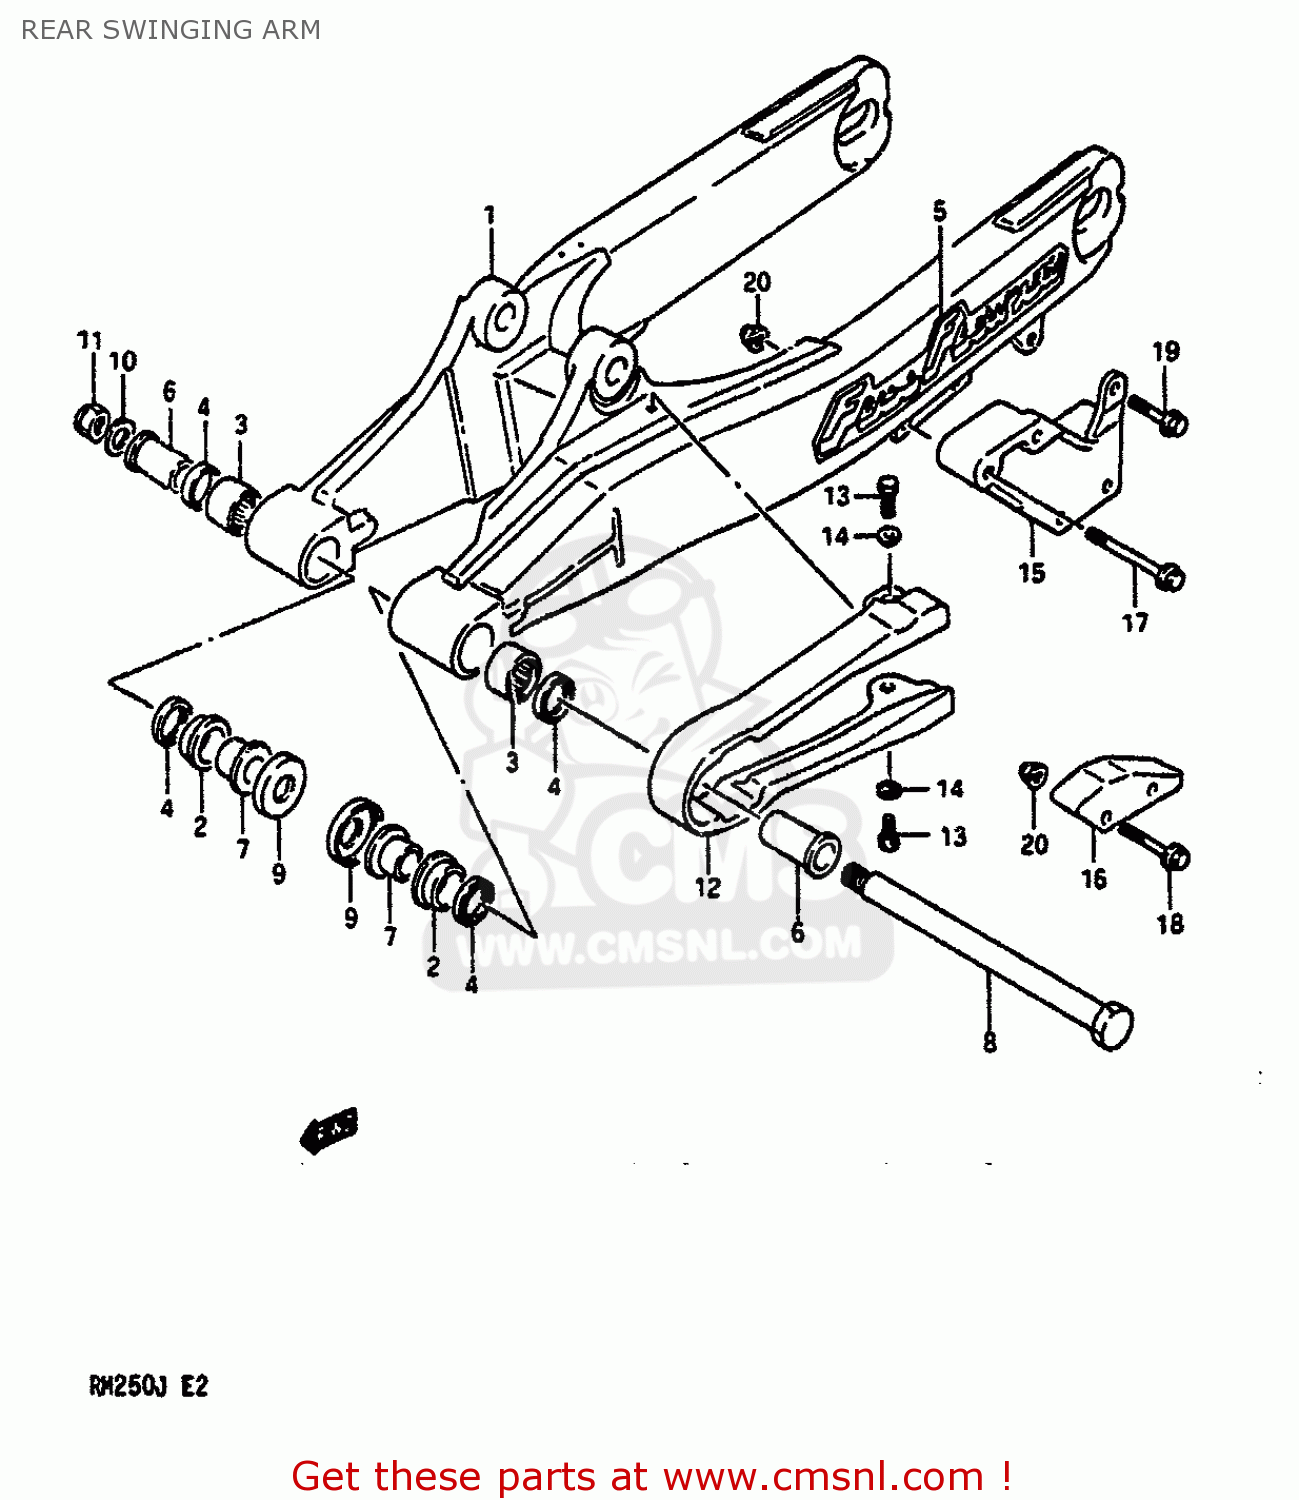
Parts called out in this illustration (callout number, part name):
1	SWING ARM ASSEMBLY,REAR
2	BUSHING,REAR SWING ARM PIVOT
3	BEARING(20X27X30)
4	OIL SEAL
5	LABEL (FRONT CARRIER WARNING)
6	SPACER,RR SWINGING ARM PIVOT
7	SPACER,RR SWGARM PIVOT INNER
8	SHAFT,RR SWINGINGARM PIVOT
9	COVER,RR SWGARM DUST SEAL
10	WASHER(14.5X29X2.3)
11	NUT
12	BUFFER,CHAIN TOUCH DEFENSE
13	BOLT
14	WASHER
15	GUIDE,CHAIN
16	DEFENSE,CHAIN GUIDE
17	BOLT
18	BOLT,UNDER
19	BOLT 6X20
20	NUT
